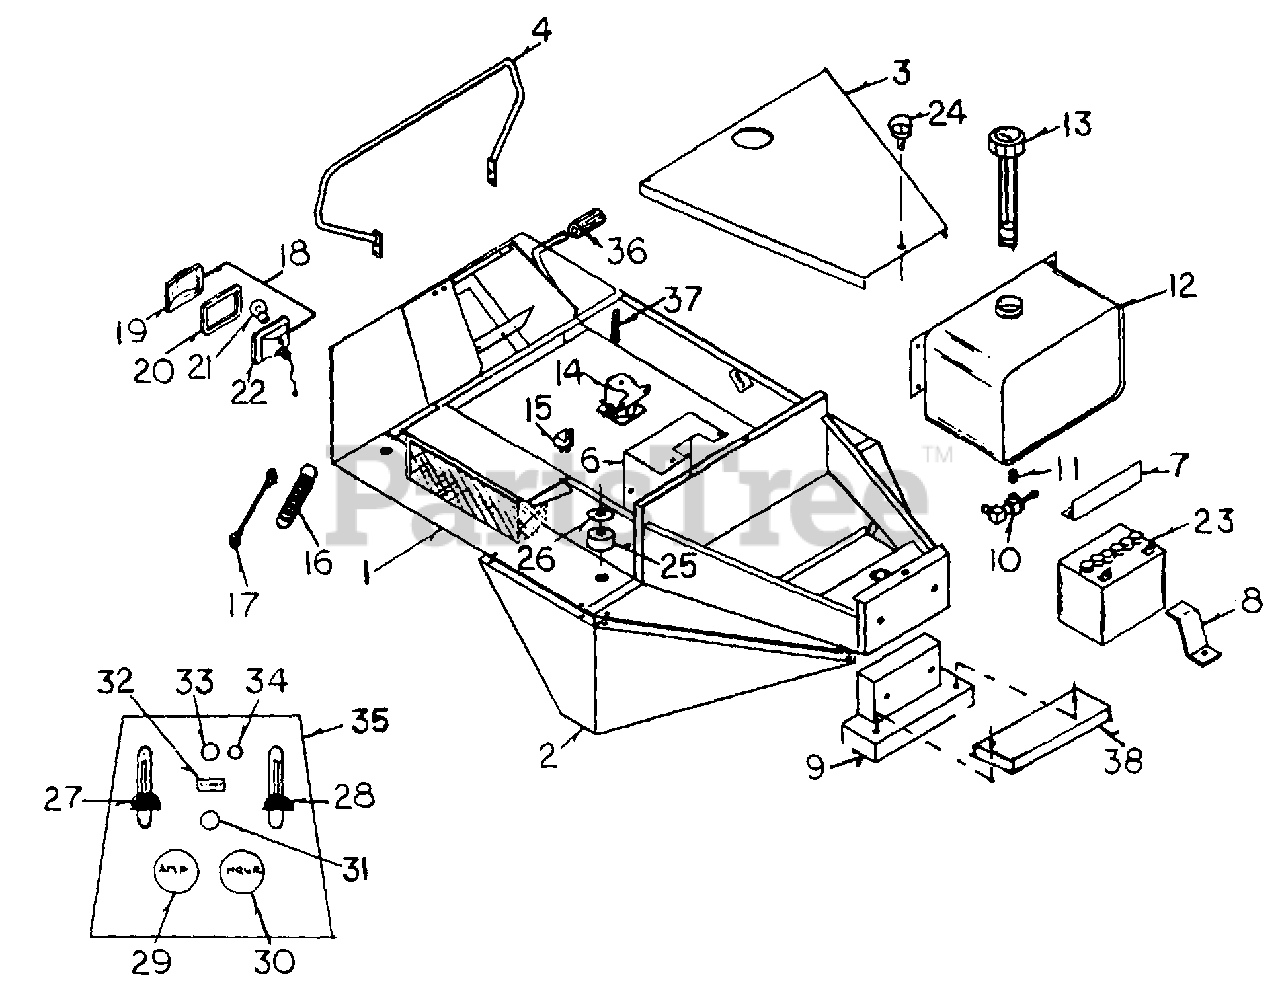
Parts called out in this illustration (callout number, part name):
1	Body
6	Oil Tank Mount
8	Battery Post Protector
10	Shutoff Valve, Fuel
13	Fuel Tank Cap w/ Gauge
15	Relay
17	Deck Lift Cable
18	Light Assembly
19	Lens
20	Gasket
21	Bulb
23	Battery
25	Rubber Body Mount
26	Body Mount Washer
28	Throttle Cable
31	Ignition Switch
32	Light Switch
33	Clutch Switch
36	Brake Pedal Pad
38	Tail Weight, 13 lb.
